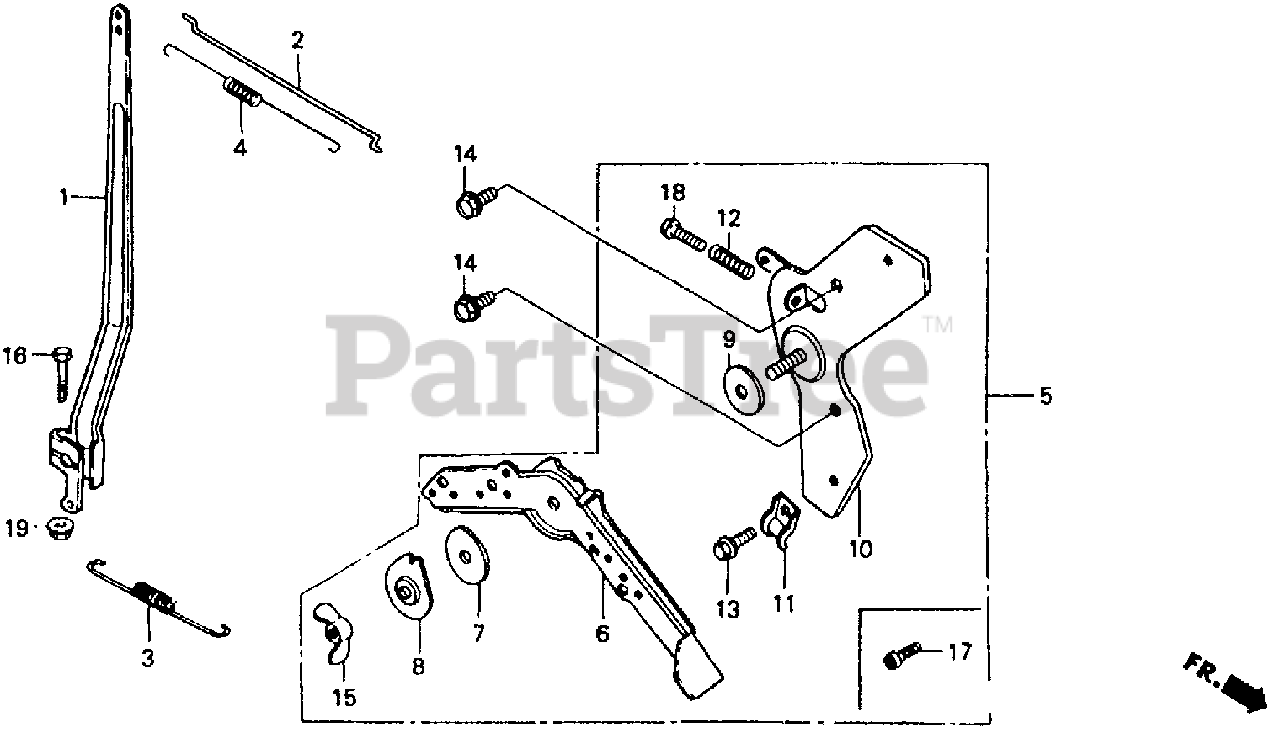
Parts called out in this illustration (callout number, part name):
1	ARM, GOVERNOR
2	ROD, GOVERNOR
3	SPRING, GOVERNOR
4	SPRING, THROTTLE RETURN
5	CONTROL ASSY.
6	LEVER, CONTROL
7	SPRING, LEVER
8	WASHER, CONTROL LEVER
9	SPACER, CONTROL LEVER
10	BASE, CONTROL LEVER
11	HOLDER, CONTROL CABLE
12	SPRING, CONTROL ADJUSTING
13	BOLT, FLANGE (5X10)
14	BOLT, FLANGE (6X12) (CT200)
15	WINGNUT (6MM)
16	BOLT, GOVERNOR ARM
17	SCREW, PAN (5X10)
18	SCREW, PAN (5X22)
19	NUT, FLANGE (6MM)
